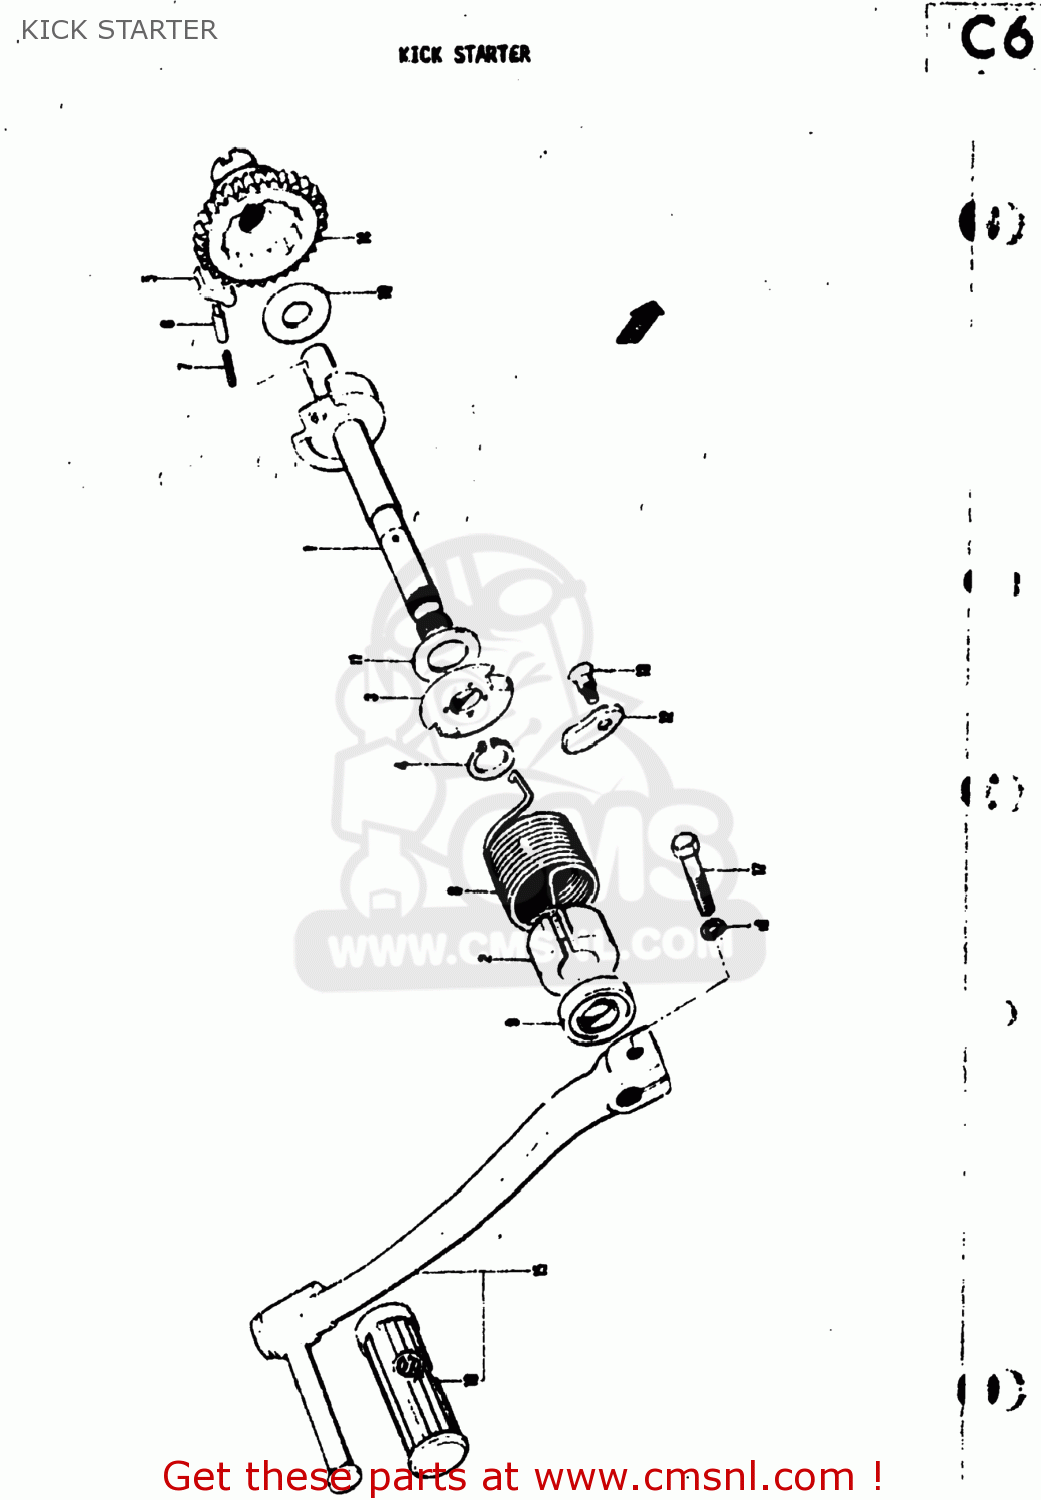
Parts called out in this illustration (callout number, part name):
1	SHAFT,KICK STARTER
2	GUIDE,KICK SHAFT SPRING
3	HOLDER,KICK STARTER SHAFT SPR
4	CIRCLIP
5	PAWL,KICK STARTER
6	PIN
7	SPRING
8	SPRING
9	SEAL,OIL(14X24X6)
10	WASHER
11	WASHER
12	LIFTER,KICK STARTER PAWL
13	SCREW(6X19)
14	GEAR,KICK STARTER DRIVE
15	LEVER ASSEMBLY,KICK STARTER
16	RUBBER,KICK STARTER PEDAL
17	BOLT
18	LOCK WASHER
